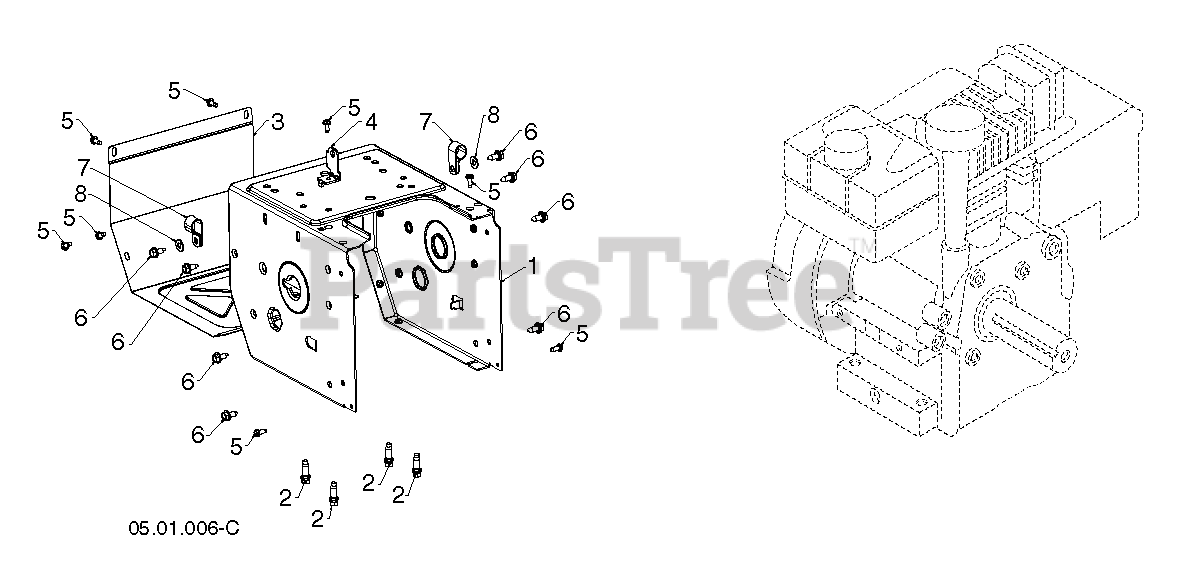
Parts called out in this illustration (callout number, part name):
1	FRAME.GEAR.CASE.SNOW.BLACK
2	BOLT 3/8-16X1-1/8
3	Snow Frame Cover, Black
4	BRACKET.SHIFTER.BZP
5	SCREW 14-20 X 5/8
6	BOLT.HEX.HD.WASHER.5/16-18X.75
7	CLIP.CABLE.BLK
8	WASHER.FLAT.343X.750X16 GA BLK
